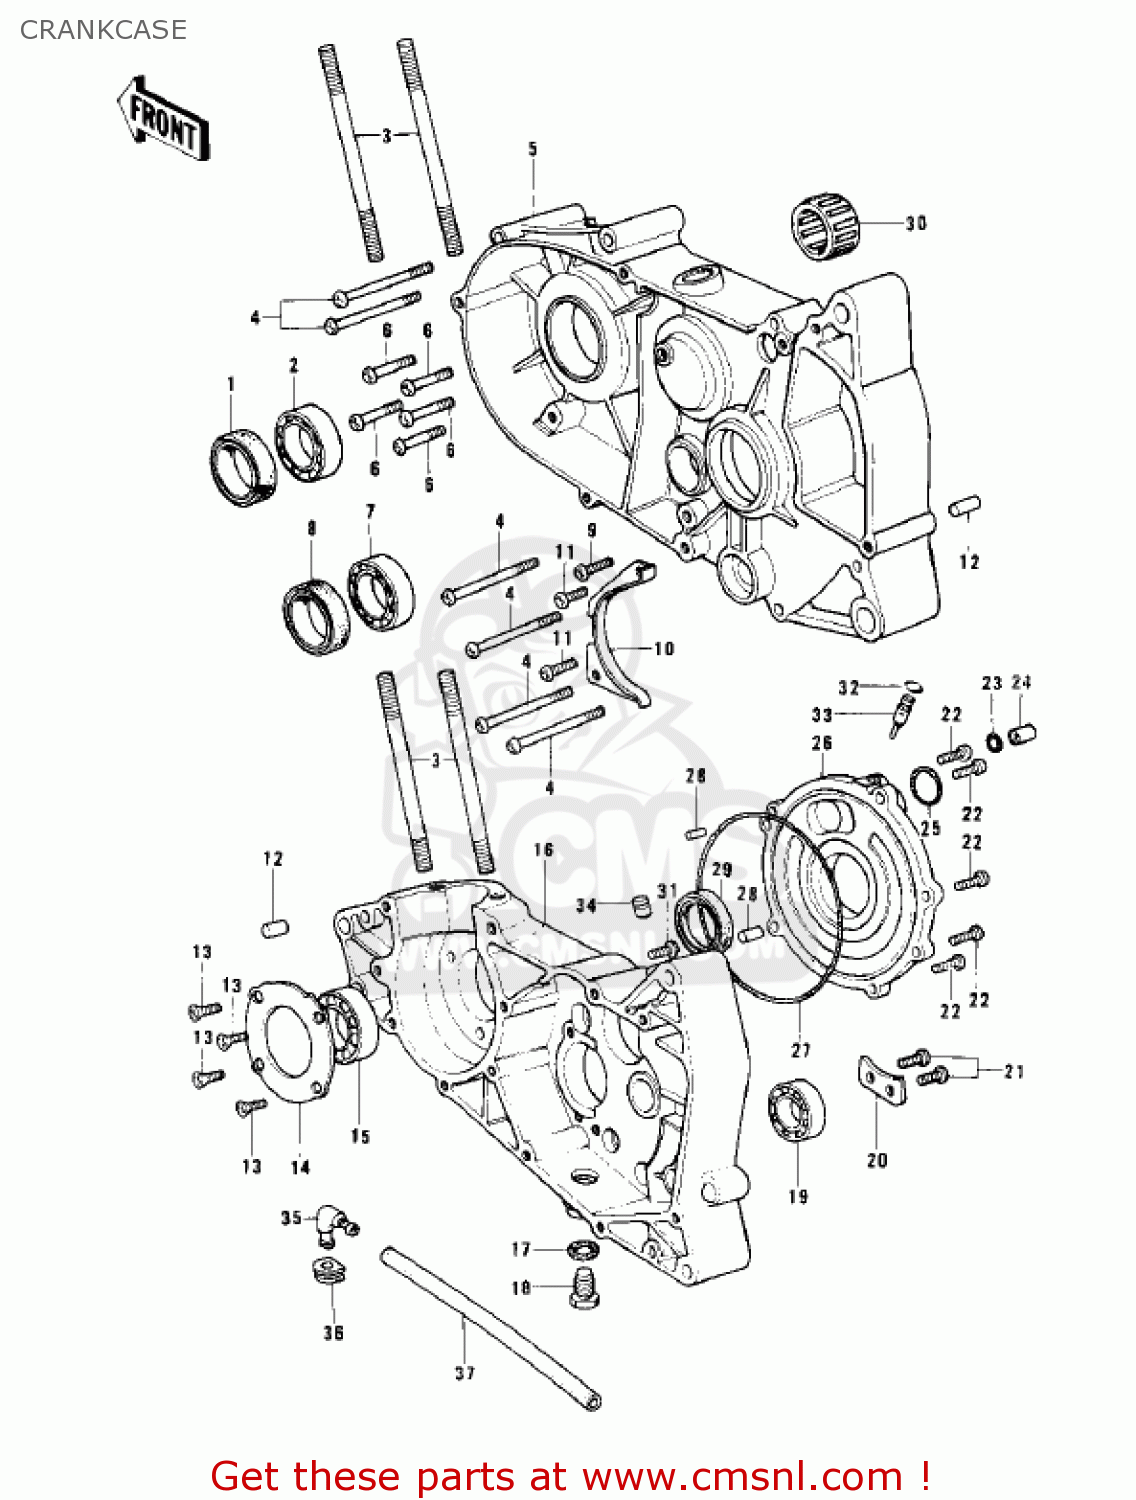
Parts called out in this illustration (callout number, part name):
1	SEAL-OIL
2	BEARING-BALL,#6204C3
3	STUD,8X70
4	SCREW-PAN HEAD,6X60
5	CRANKCASE,LH BLACK
6	SCREW-PAN HEAD,6X40
7	BEARING-BALL,#6004C3
8	OIL SEAL SC25376
9	SCREW-PAN HEAD,6X20
10	GUIDE-CHAIN
11	SCREW-PAN HEAD,6X12
12	PIN,DOWEL,10X8.2X14
13	SCREW-CNTSNK HD,6X16
14	PLATE,CRANK BEARING
15	BEARING-BALL,#6304C3
16	CRANKCASE,R.H,BLACK
17	GASKET,12.5X18X1,DRAI (NAS)
18	PLUG,DRAIN
19	BEARING-BALL,#6203C3
20	PLATE,MISSION BEARNG
21	SCREW-PAN HEAD,6X12
22	SCREW-PAN HEAD,6X20
23	RING-O,7.8X3.5
24	DOWEL PIN
25	O RING,28MM
26	COVER,ROTARY DISC
27	RING-O,107.4X1.9
28	ROLLER,5X12
29	SEAL-OIL
30	BEARING-NEEDLE,36BDM4
31	SCREW-PAN HEAD,6X25
32	RING-O,2.5X1.5
33	NOZZLE
34	PLUG,15X19
35	BREATHER
36	GROMMET
37	BREATHER
